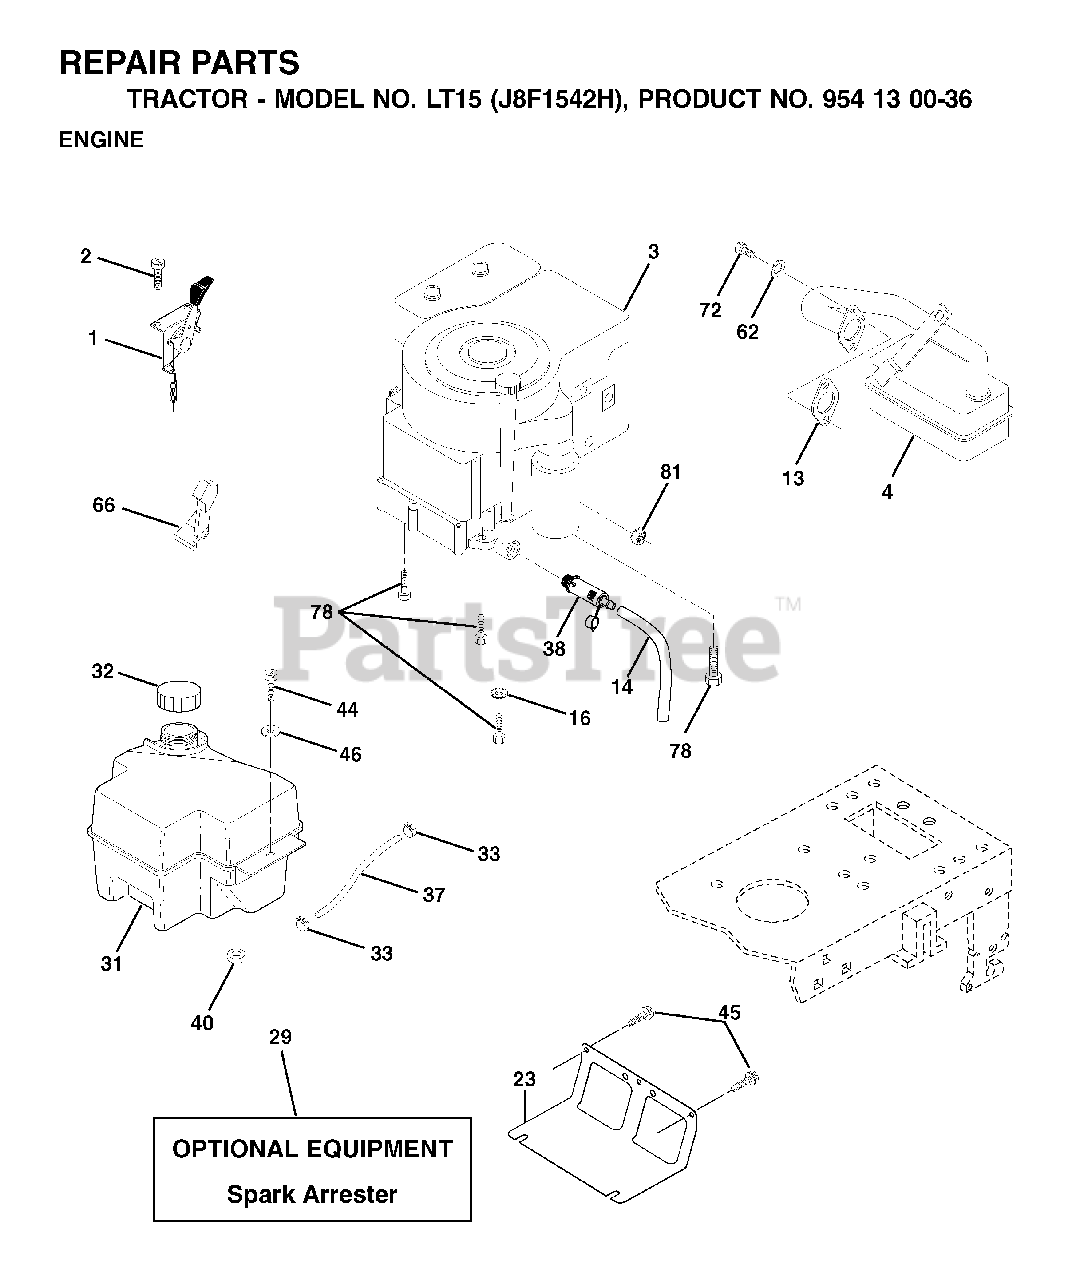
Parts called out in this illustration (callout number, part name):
1	THROTTLE CONTROL CABLE
2	SCREW LT
13	REPL BY 532 27 22-93
14	TUBE, DRAIN OIL ASM.
16	LOCKWASHER
23	SHEILD.BROWNING.DBR.GUARD
29	ARRESTER SPARK (OPTIONAL)
31	TANK, 2GAL
32	FUEL CAP
33	HOSE CLAMP
37	LINE.FUEL.20
38	PLUG, OIL DRAIN EASY
40	GROMMET T
44	SCREW HEXWSHR 1/4-20X3/4
45	SCREW, 3/8-16X3/4
62	LOCKWASHER
66	STOP THROTTLE
72	SCREW
78	SCREW.3/8-16
81	NUT
